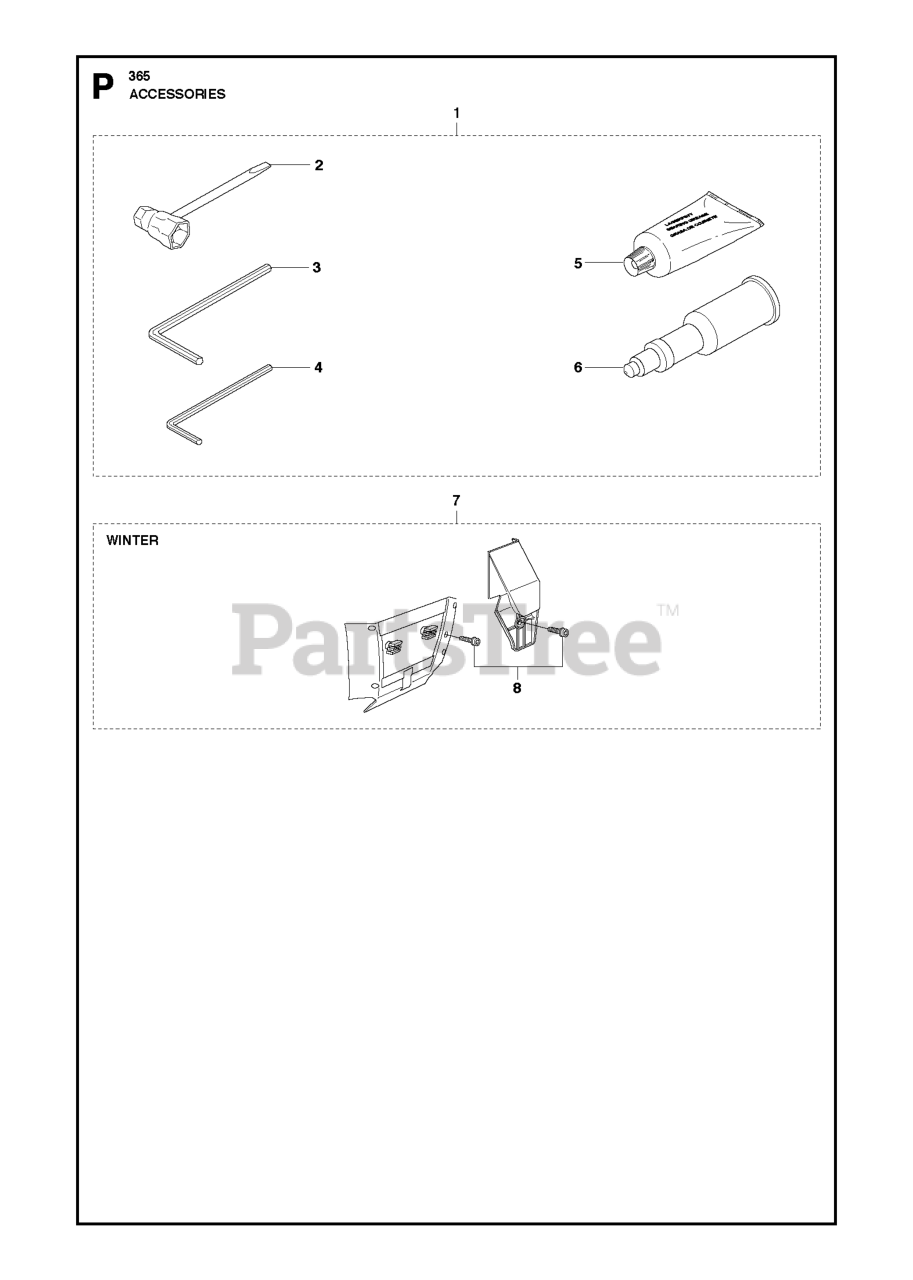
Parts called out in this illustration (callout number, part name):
1	TOOL KIT
2	COMBI TOOL
3	L-SPANNER
4	L-SPANNER
5	GREASE
6	Grease Gun
7	WINTER KIT
